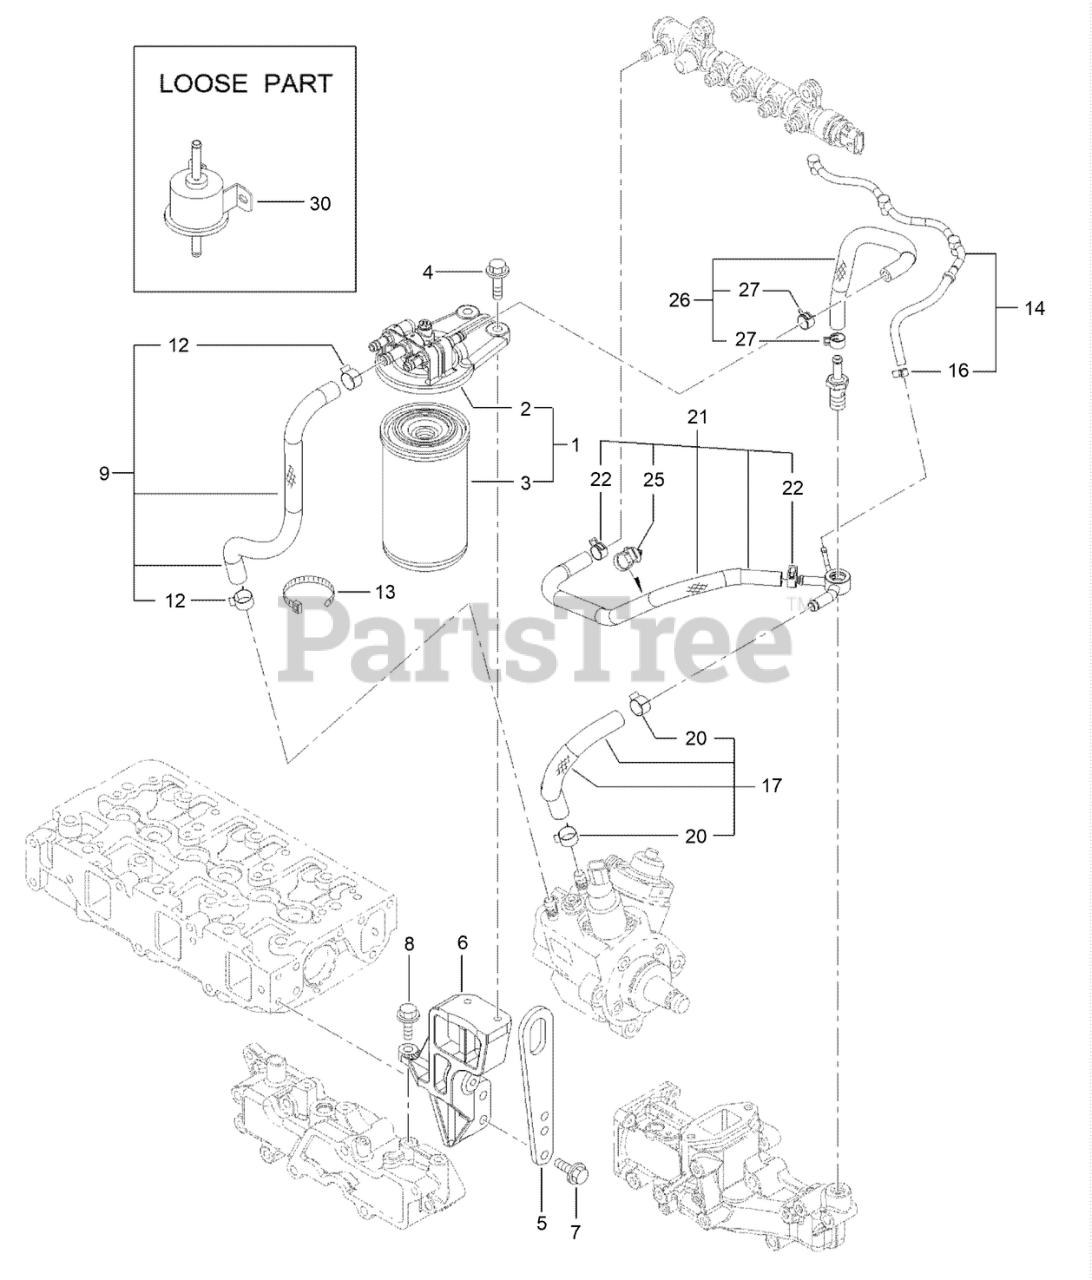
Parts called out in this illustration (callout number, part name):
1	FUEL/OIL FILTER ASM
2	FUEL/OIL FILTER BRACKET ASM
3	FILTER-FUEL
5	LIFTER
6	FILTER BRACKET ASM
9	FUEL PIPE ASM
12	CLAMP-HOSE
14	JOINT-HOSE, 4 WAY
16	CLAMP-HOSE
17	FUEL PIPE ASM
20	CLAMP-HOSE
21	FUEL PIPE ASM
22	CLIP-HOSE
25	BAND-CLIP
26	FUEL PIPE ASM
27	CLIP-HOSE
30	PUMP-FUEL, ELECTRIC
